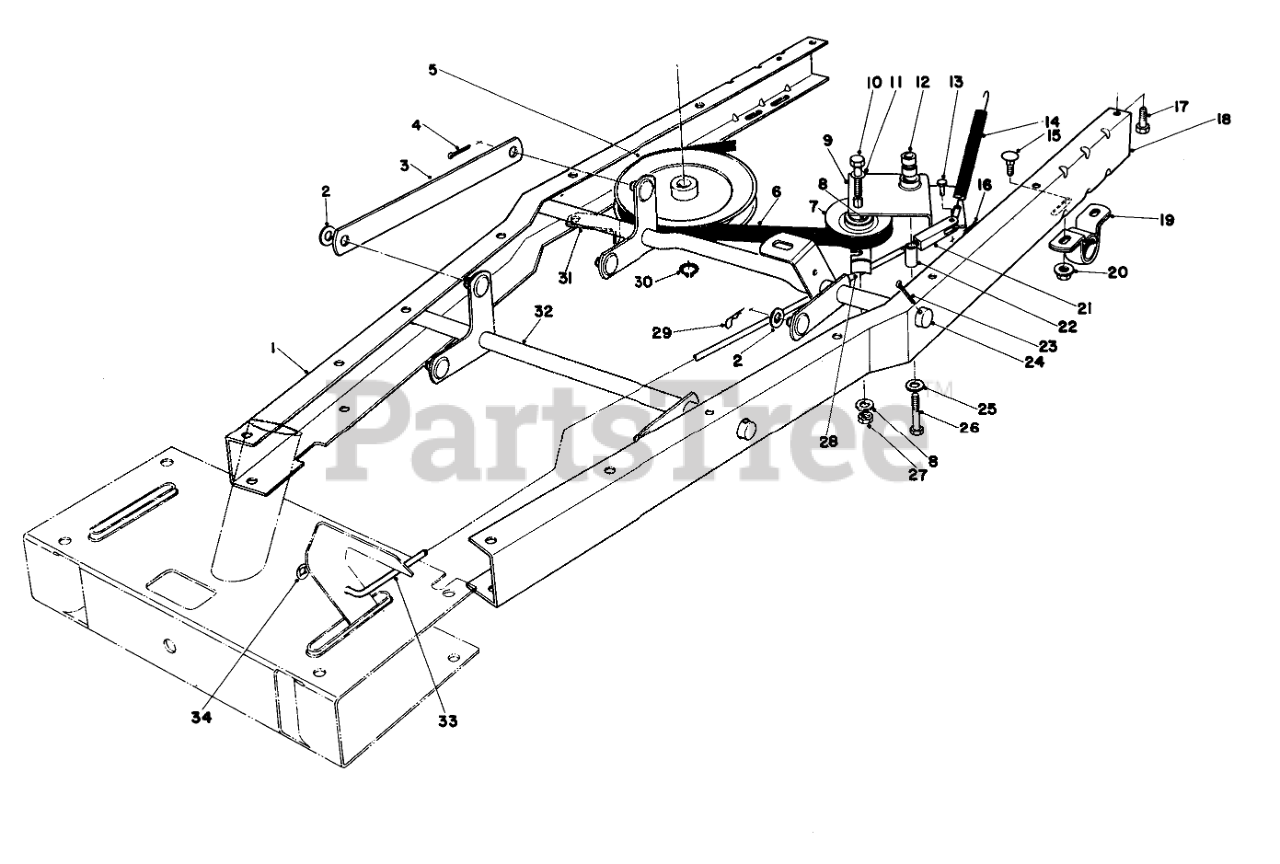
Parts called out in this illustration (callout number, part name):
1	Frame-Channel R.H.
2	WASHER-FLAT
3	Linkage-Height Adj.
4	PIN-COTTER
5	Pulley
6	V-BELT
7	PULLEY-IDLER
8	WASHER-FLAT
9	Traction Idler (Incl . Ref #12)
10	SCREW-HH
11	Washer
12	Bushing
13	PIN-CLEVIS
14	Clutch Tension Spring
15	SCREW-CARR
16	Cotter Pin
17	Screw
18	LH FRAME CHANNEL B
19	PILLOW BLOCK
20	NUT-HF
22	PIVOT SPACER
23	Cotter Pin
24	REAR HT ADJ WA B
25	WASHER-PLAIN
26	SCREW-HH
27	NUT-LOCK, SIDE
28	RETAINER-BELT
29	PIN-COTTER
30	RING-SNAP, EXTERNAL
31	TRANS BELT RET B
32	FRONT LIFT WA B
33	Clutch Rod
34	PUSH ON SPEED NUT 1/4
